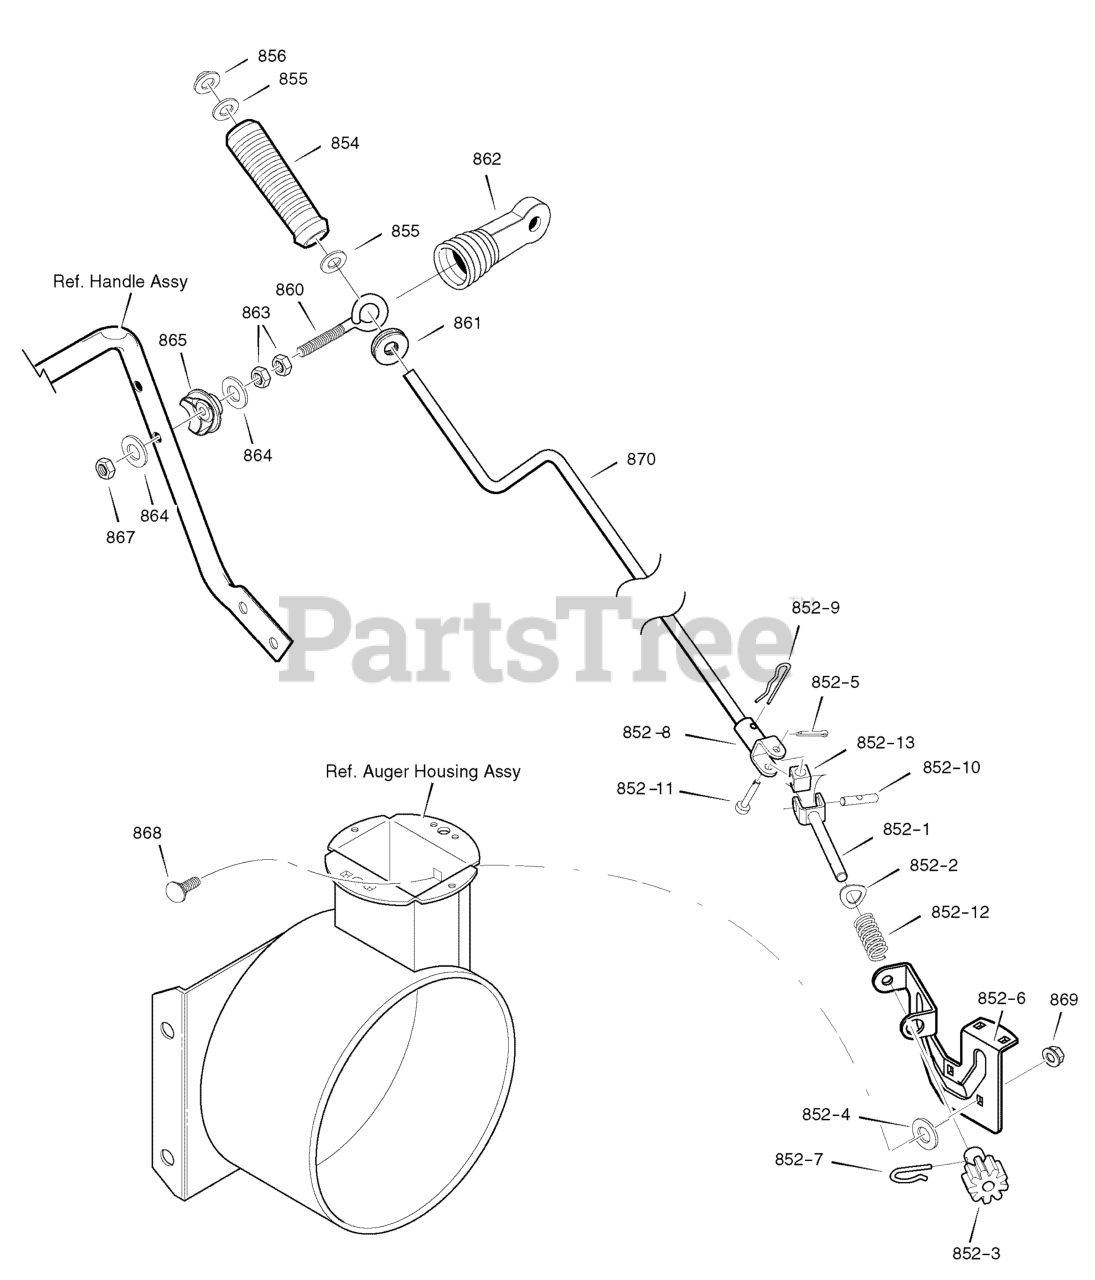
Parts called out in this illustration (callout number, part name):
852-1	YOKE & ROD ASSEMBLY
852-2	WASHER, CURVED SPRING
852-3	GEAR, CHUTE ROTATION 9T
852-5	PIN, COTTER
852-6	BRACKET, CHUTE GEAR
852-7	PIN, HAIR
852-8	YOKE ADAPTER YZ, ASSEMBLY
852-9	PIN, HAIR
852-10	PIN, UNIVERSAL JOINT
852-11	PIN, CLEVIS
852-12	SPRING, COMPRESSION
852-13	HOUSING, UNIVERSAL
854	KNOB, SLEEVE
855	FLATWASHER
856	NUT, PUSH ON 3/8"
860	EYE BOLT 3/8-16 X 6.50
861	GROMMET, EYE BOLT
862	BOOT, EYE BOLT
863	NUT, 3/8-16 HEXJAM
864	WASHER, Flat, 13/32
865	ADAPTER, BOOT
867	NUT, 3/8-16 HEXNYL
868	BOLT, CARRIAGE 1/4-20 X 1.00
869	NUT, 1/4-20
870	CRANK, ASSEMBLY CHUTE
